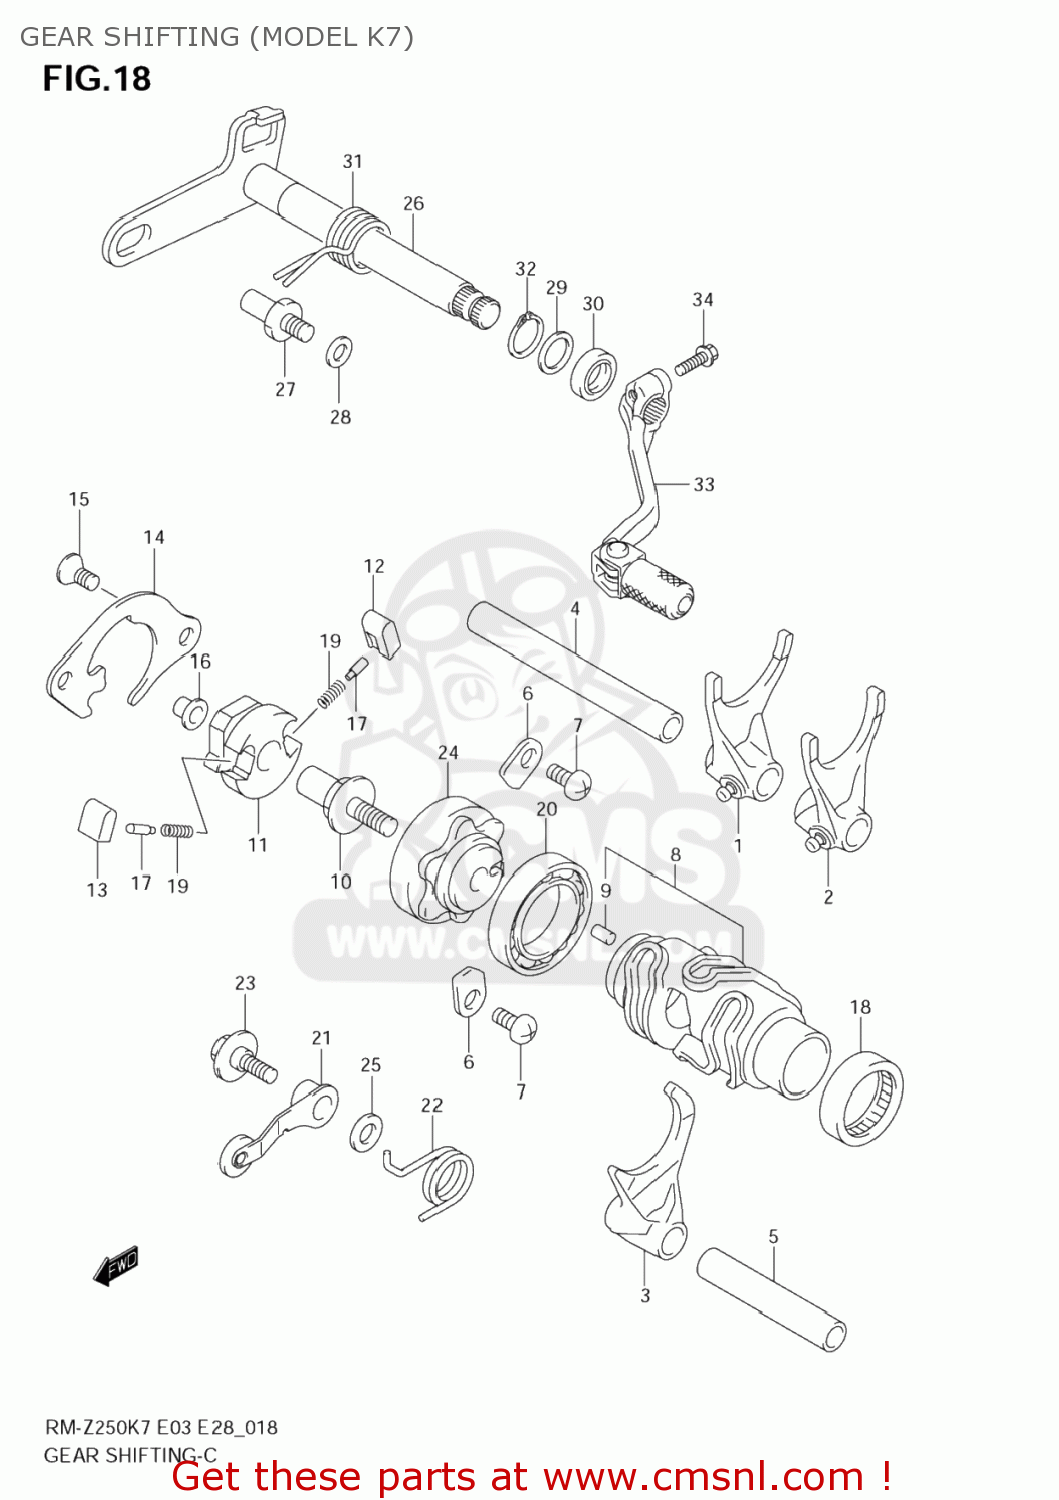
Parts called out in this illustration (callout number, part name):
1	FORK,GEAR SHIF
2	FORK,GEAR SHIF
3	FORK,GEAR SHIF
4	SHAFT,GEAR SHIFT FORK(L:95)
5	SHAFT,GEAR SHIFT FORK(L:60)
6	RETAINER
7	BOLT(6X12)
8	CAM COMP,GEAR
9	PIN(4X11.2)
10	PIN,GEAR SHIFT CAM
11	SHIFTER,GEAR SHIFT CAM
12	PAWL,GEAR SHIFT NO.1
13	PAWL,GEAR SHIFT NO.2
14	LIFTER,GEAR SHIFT PAWL
15	SCREW(6X12)
16	SPACER(7X10X5)
17	PIN
18	BEARING(25X32X12)
19	SPRING
20	BEARING
21	STOPPER,GEAR SHIFT CAM
22	SPRING,GEAR SHIFT CAM STOPPER
23	BOLT,SHIFT CAM STOPPER
24	PLATE,GEAR SHIFT CAM STOPPER
25	WASHER
26	SHAFT,GEAR SHIFT
27	STOPPER,GEAR SHIFT ARM
28	SHIM(8.8X14X1)
29	SHIM(14X20X1)
30	SEAL,OIL(14X22X6)
31	SPRING
32	CIRCLIP
33	LEVER ASSY,GEAR
34	BOLT
